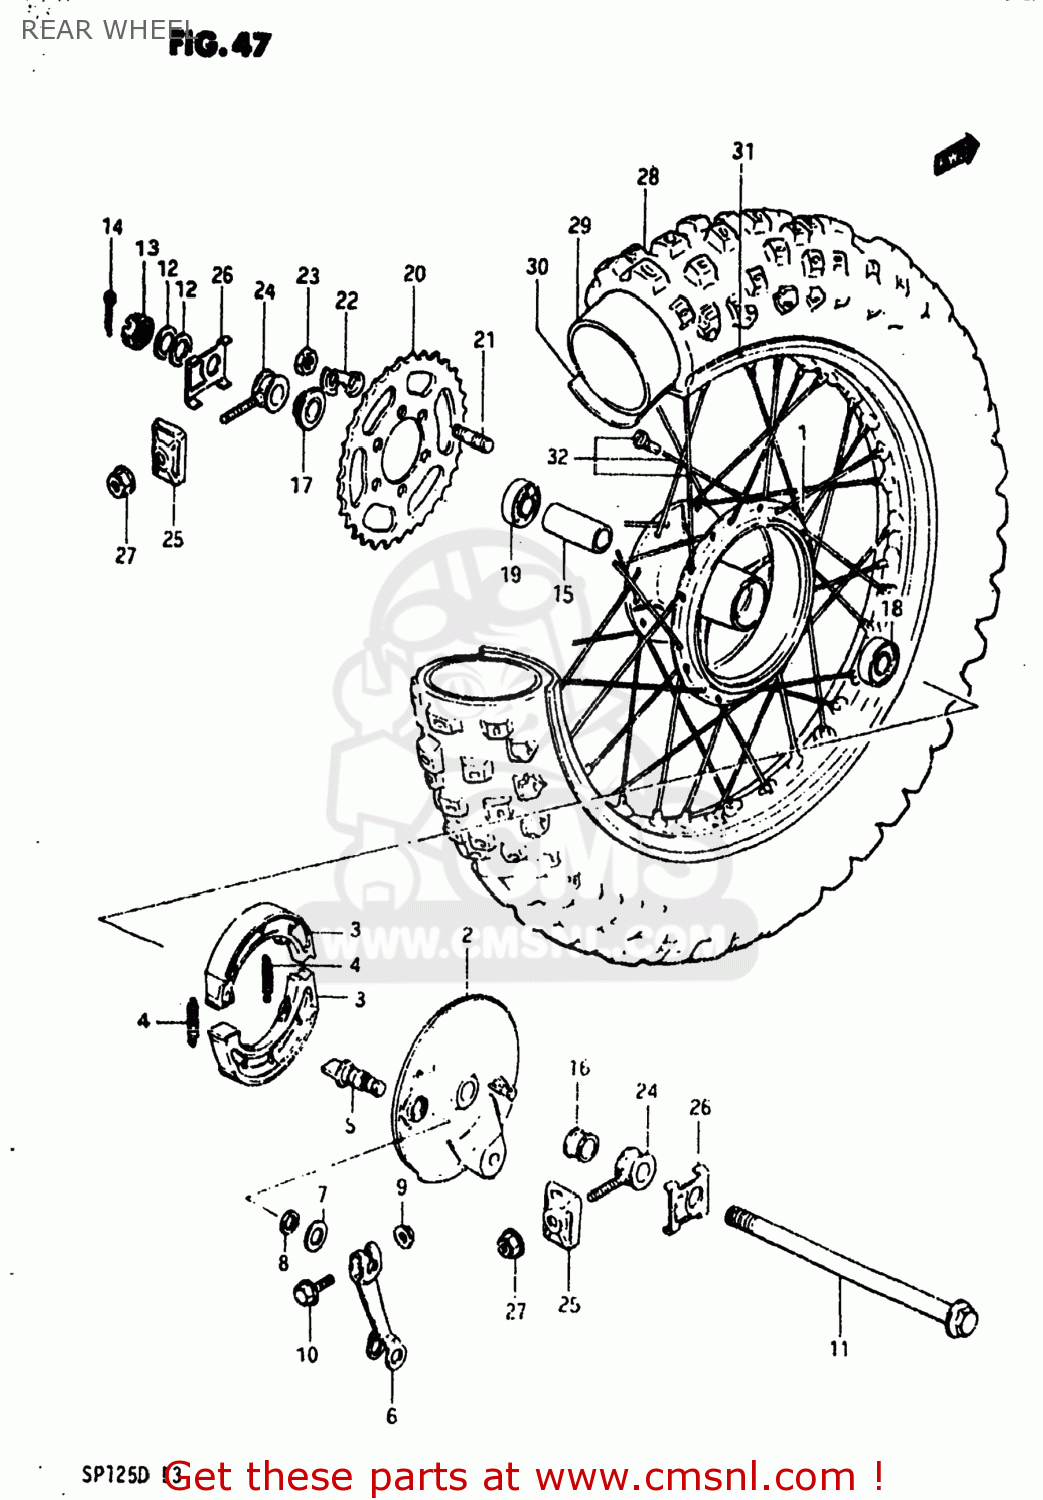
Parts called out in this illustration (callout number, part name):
1	HUB,REAR WHEEL
2	PANEL,RR BRAKE ANCHOR
3	SHOE,BRAKE
4	SPRING(L:34)
5	CAM,FRONT BRAKE
6	LEVER,RR BRAKE CAM
7	WASHER (14.5X22X1.6)
8	O-RING (D:2.4 ID:13.8)
9	NUT
10	BOLT
11	AXLE,REAR
12	WASHER
13	NUT
14	COTTER PIN
15	SPACER(15.3X21.7X107.5)
16	SPACER,RR AXLE,R
17	SPACER,REAR AXLE,LEFT
18	BEARING
19	BEARING
20	SPROCKET,RR(NT:47)
21	BOLT,STUD
22	WASHER
23	NUT
24	ADJUSTER,CHAIN
25	PLATE,CHAIN ADJUSTER
26	WASHER,CHAIN ADJUSTER GUIDE
27	NUT
28	TIRE
29	TUBE ASSEMBLY,WHEEL,INNER
30	PROTECTOR,INNER TUBE
31	RIM,REAR WHEEL
32	SPOKE SET
